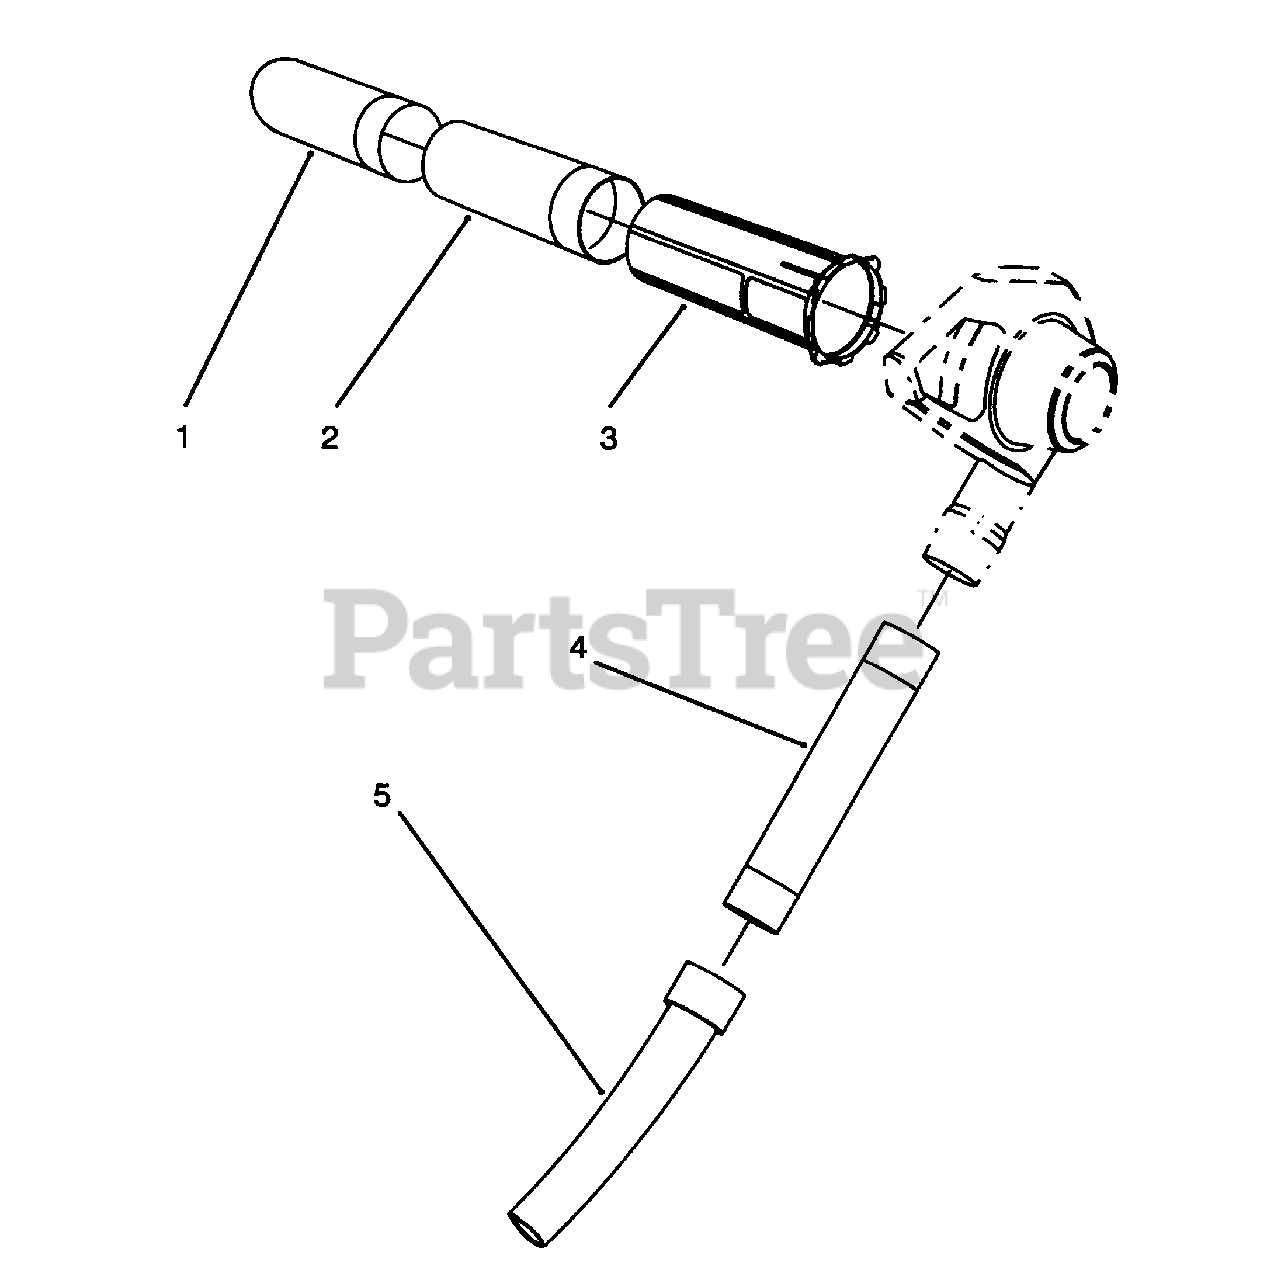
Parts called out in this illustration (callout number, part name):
1	Vac Tube-Lower
2	Vac Tube-Middle
3	Vac Tube-Upper
4	Tube-Blower
